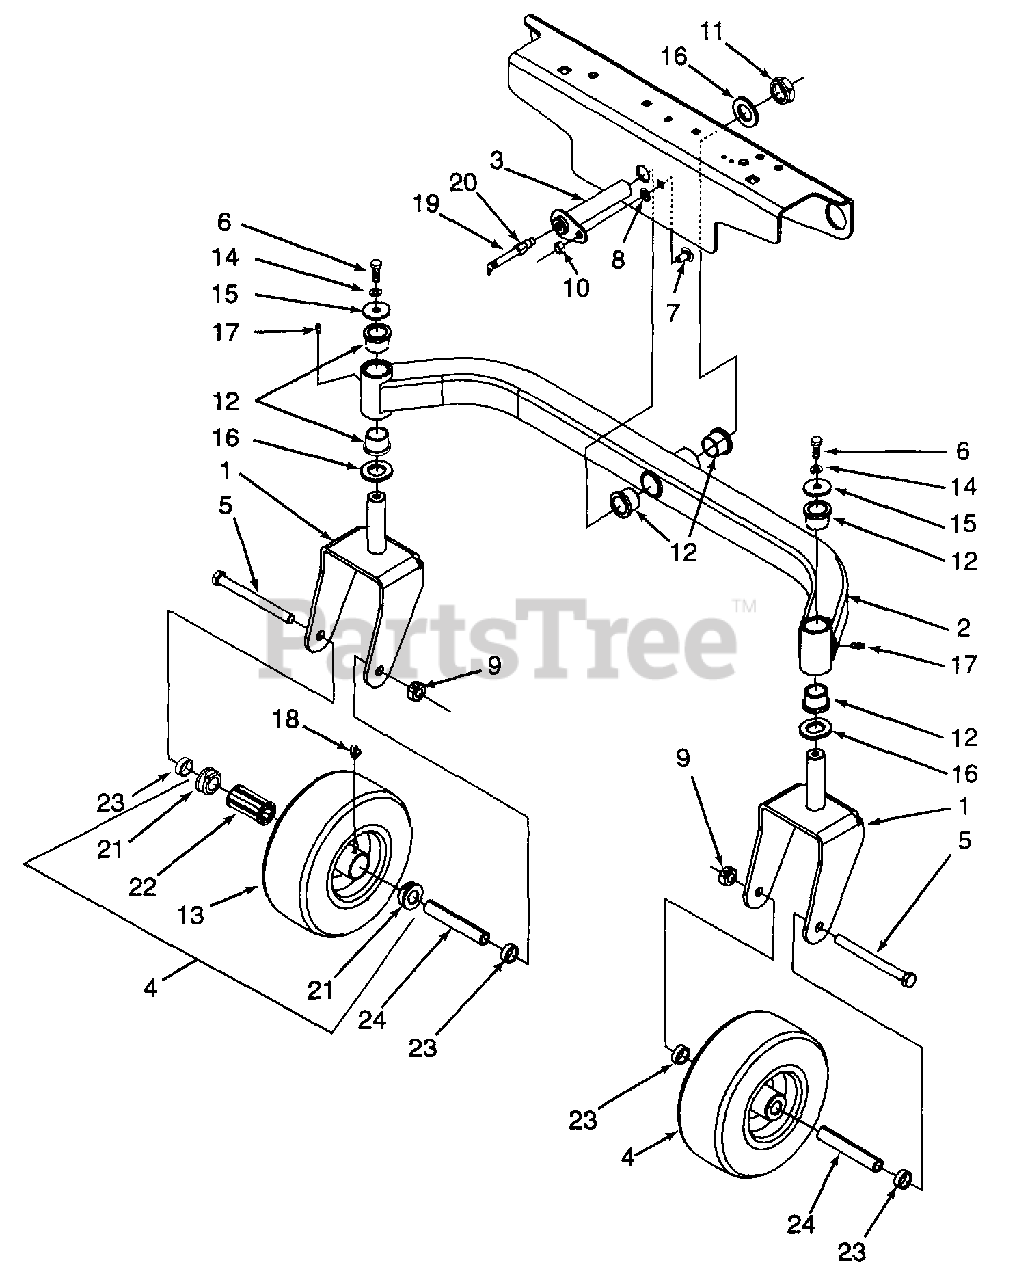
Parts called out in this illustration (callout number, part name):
4	Wheel Ass'y, 9.0 x 3.70-4
5	Screw, Hex Cap, 1/2-20 x 5.5
6	Screw, Hex Cap, 3/8-16 x 1.0 GR5
7	Bolt, Carriage, 3/8-16 x .75
8	Bush Nut, Retainer, 3/8 ID
9	Nut, Hex Center Lock, 1/2-20
10	Nut, Hex Flange Lock, 3/8-16
11	Nut, Hex Lock, 1.0-14
12	Bearing, Flange, 1.0 ID
13	Tire, Urethane, Only
14	Washer, Lock 3/8
15	Washer, Flat, .39 x 1.5 x .134
16	Washer, Special Flat
17	Fitting, Grease
18	Fitting, Grease, 90° Tap 1/4-28
19	Fitting, Grease, 65° w/Extension
20	Adapter, 1/8 NPTF x 1/8 NPTF
21	Bearing, Flange
22	Bearing, Roller
23	Spacer, .79 ID x .347 Lg
24	Spacer, Wheel
